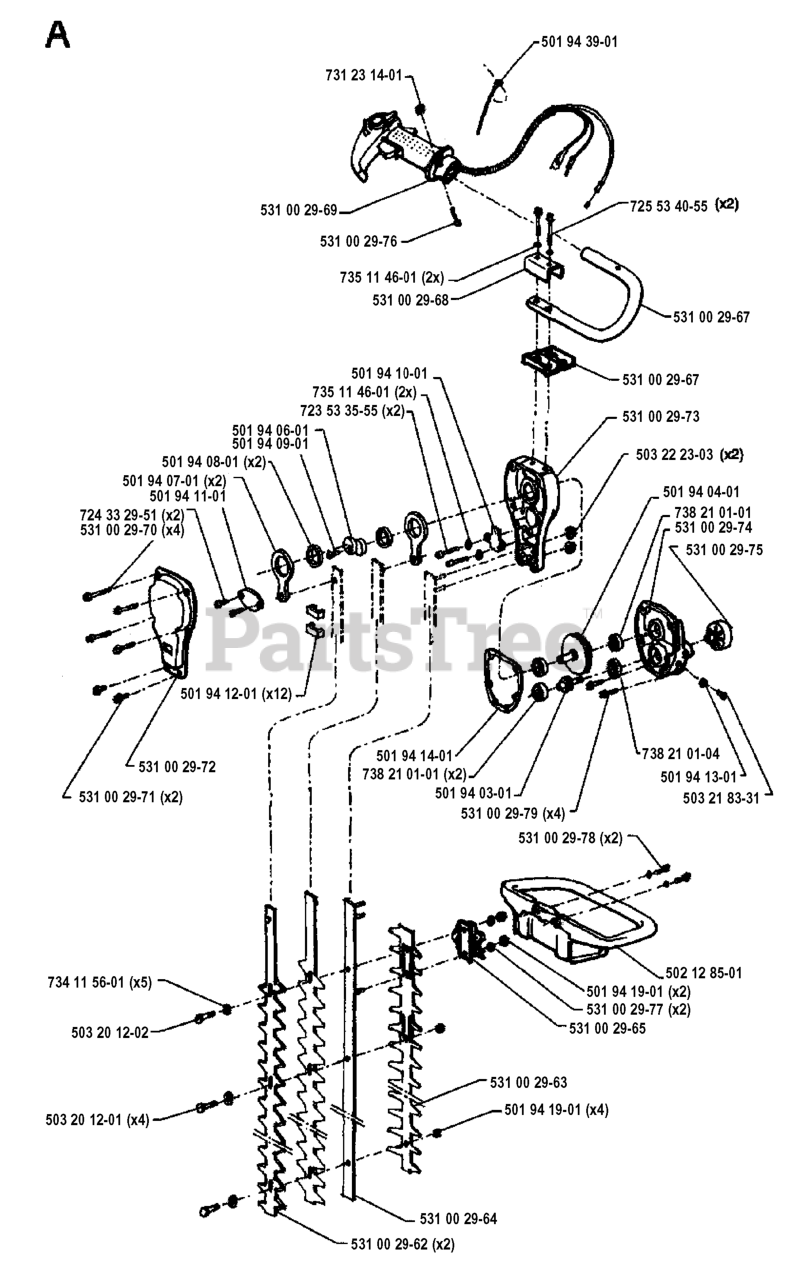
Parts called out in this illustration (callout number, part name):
2	DRAWBAR
3	SCREW 3/8-16X3/4
5	BUMPER.RUBBER.HOOD
9	DASH
10	BOLT D
11	PANEL DASH LH
13	PANEL DASH RH
17	HOOD
18	BUMPER HOOD T
20	PLATE MTG
23	BUSHING.SNAP.NYL.BLK.
25	WASHER
26	NUT
28	GRILL
29	LENS
30	FENDER FOOTREST
31	BRACKET.SUPPORT.FENDER
37	Screw 5/16-18 x 1/2 Hex, Self Tapping 5/16-18 x 1/2
38	BRACKET
52	WASHER
53	BRACKET PNT PICK OFF LT/PL
57	BOLT
58	AIR DUCT P/L/LT
60	Bolt - Rd. Hd. Sq. Neckiage 3/8 16 x 3/4
64	DASH LOWER
68	NUT
71	NUT.CROWNLOCK.1/4
129	WASHER
134	ROD SUPPORT HOOD LT/PL HUS.
142	PLATE
143	BRACKET, SWAY BAR
144	BRACKET FOOTREST
145	ROD PIVOT CHASSIS/HOOD
206	SHOULDER BOLT 5/16-18TT
207	SCREW, 5/16-18 X 1/2
208	SCREW 3/8-16X1/2
212	INSERT LENS REFLECTOR
